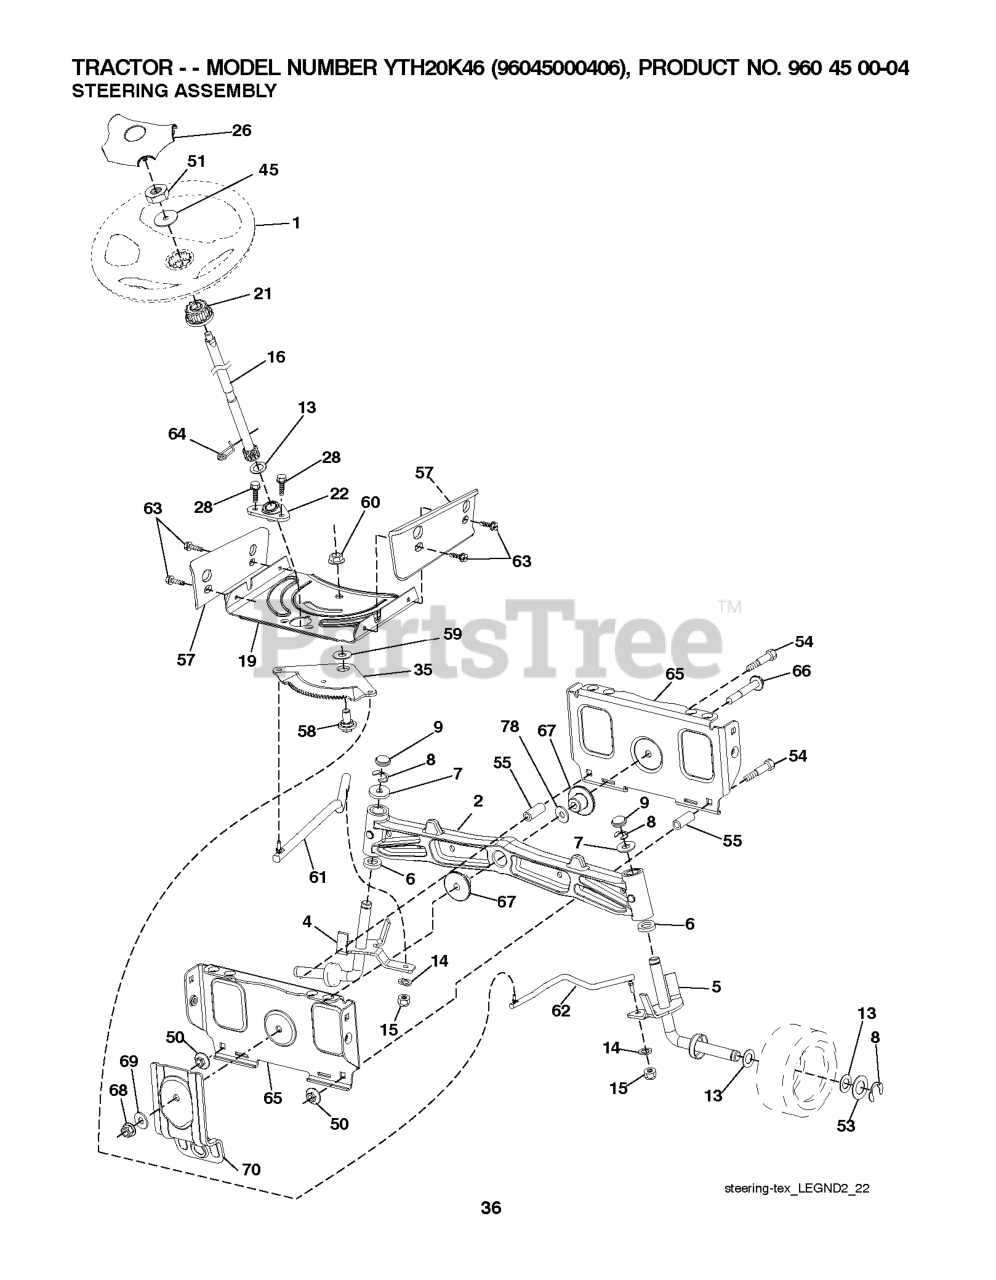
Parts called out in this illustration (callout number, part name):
1	WHEEL.STEERING.LEGEND2.GRY
2	AXLE ASSY FRONT
4	SPINDLE.WELDED.LH.15"TEX
5	SPINDLE.WELDED.RH.15"T
6	THRUST WASHER
9	CAP.SPINDLE.BLACK
14	WASHER, LOCK 3/8
15	NUT CROWNLOCK 3/8-24
16	SHAFT, STEERING
19	PLATE.STEER.DDL.NLT/NG
21	ADAPTER, WHEEL STNG..
22	BUSHING.ASM.STEERING.A
26	INSERT.CAP.STRG.WH.GRAY
28	SCREW, 3/8-16X3/4
35	GEAR.SECTOR.PLATE.DDL.
45	WASHER 9/16"ID, 2 3/8"OD
50	NUT LOCK FLG 3/8-16 UNC
51	NUT.HEX.1/2-20
53	WASHER.HARDENED
55	SPACER.BRACE.AXLE
57	BRACKET.UPSTOP.TEX
58	BOLT.SHOULDER.SECTOR.P
59	WASHER.THURST.SECTOR.S
60	NUT FLANGE LOCK 5/8-11
61	DRAGLINK.LH.BALLSTUD.D
62	DRAGLINK.RH.BALLSTUD.D
63	SCREW
64	RETAINER.CLIP.SPRING.S
65	BRACE.AXLE.FRONT.NLT/N
66	BOLT HEX FGHD 7/16-14 X 3 SERR
67	BUSHING.PM.FRONT AXLE
68	NUT.LOCK.FLANGE.7/16
69	WASHER.1.5X.505X.118
70	BRKT.DECK.SUSPENSION.F
78	THRUST WASHER
